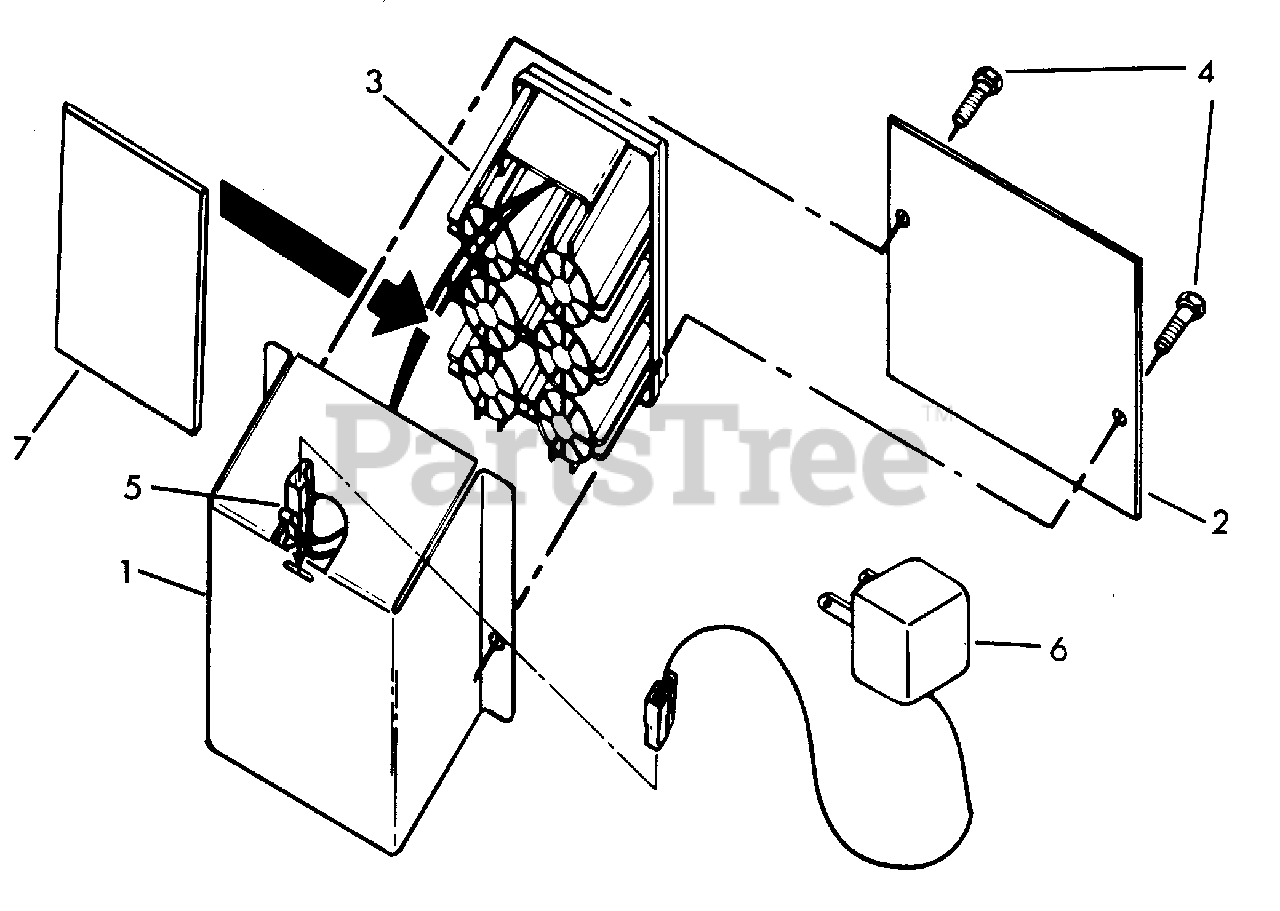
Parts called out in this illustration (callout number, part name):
1	Battery Bracket (AYP part number)
2	Battery Cover (AYP part number)
3	Battery Kit (Inc. 5,7) (AYP part number)
4	Hex Washer Head Screw (AYP part number)
5	Connector Mounting Clip (AYP part number)
6	Battery Charger (AYP part number)
7	Battery Pad (AYP part number)
